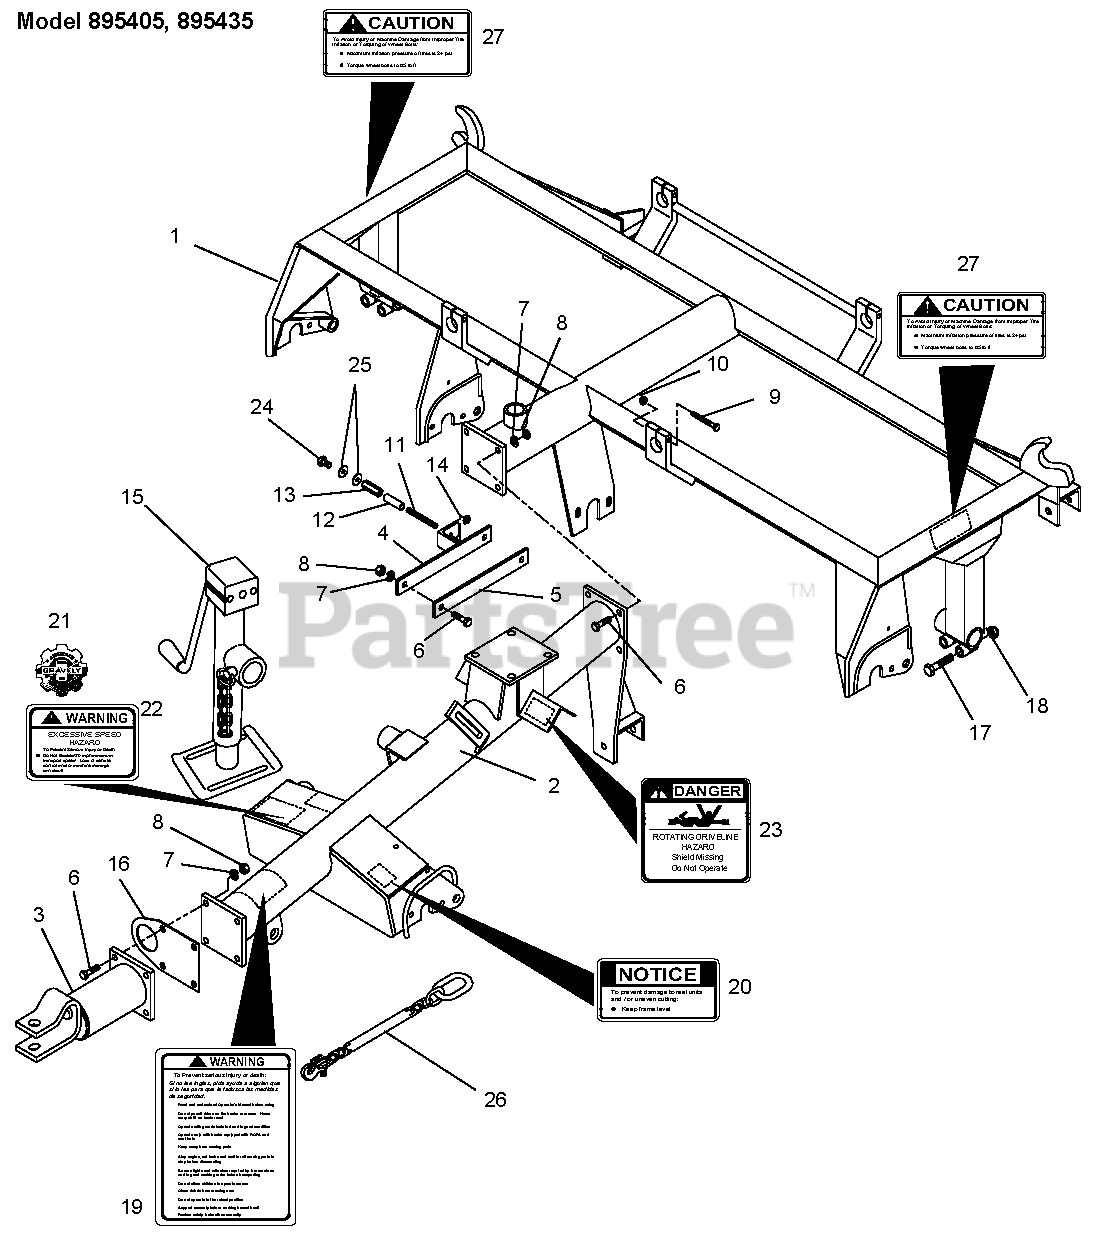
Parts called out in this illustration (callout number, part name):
1	Weldment, Mainframe
2	Tongue Assembly
3	Weldment, Clevis Hitch
4	Weldment, Tongue Brace
5	Brace, Tongue Left Hand
6	Cap Screw, Hex Head .50-13 x 1.5
7	Washer, Lock .50
8	Nut, Hex .50
9	Cap Screw, Hex Head .375-16 x 3
10	Nut, Hex .375-16
11	Stud, Belt Guard
13	Nut, Hex Coupler .375-16
14	Hex Nut .375-16 CP Nylock
15	Jack, Screw 5000 lb.
16	Holder, Hydraulic Hose
17	Cap Screw, Hex Head .50-13 x 2.5
18	Nut, Hex .50-13 Nylock
19	Decal, Warning
20	Decal, Notice
21	Decal, Gravely Heritage Small
22	Decal, Warning
23	Decal, Danger
24	Cap Screw, Hex Head .375-16 x .75
25	Washer, Flat .375
26	Chain, Safety Tow
27	Decal, Caution
